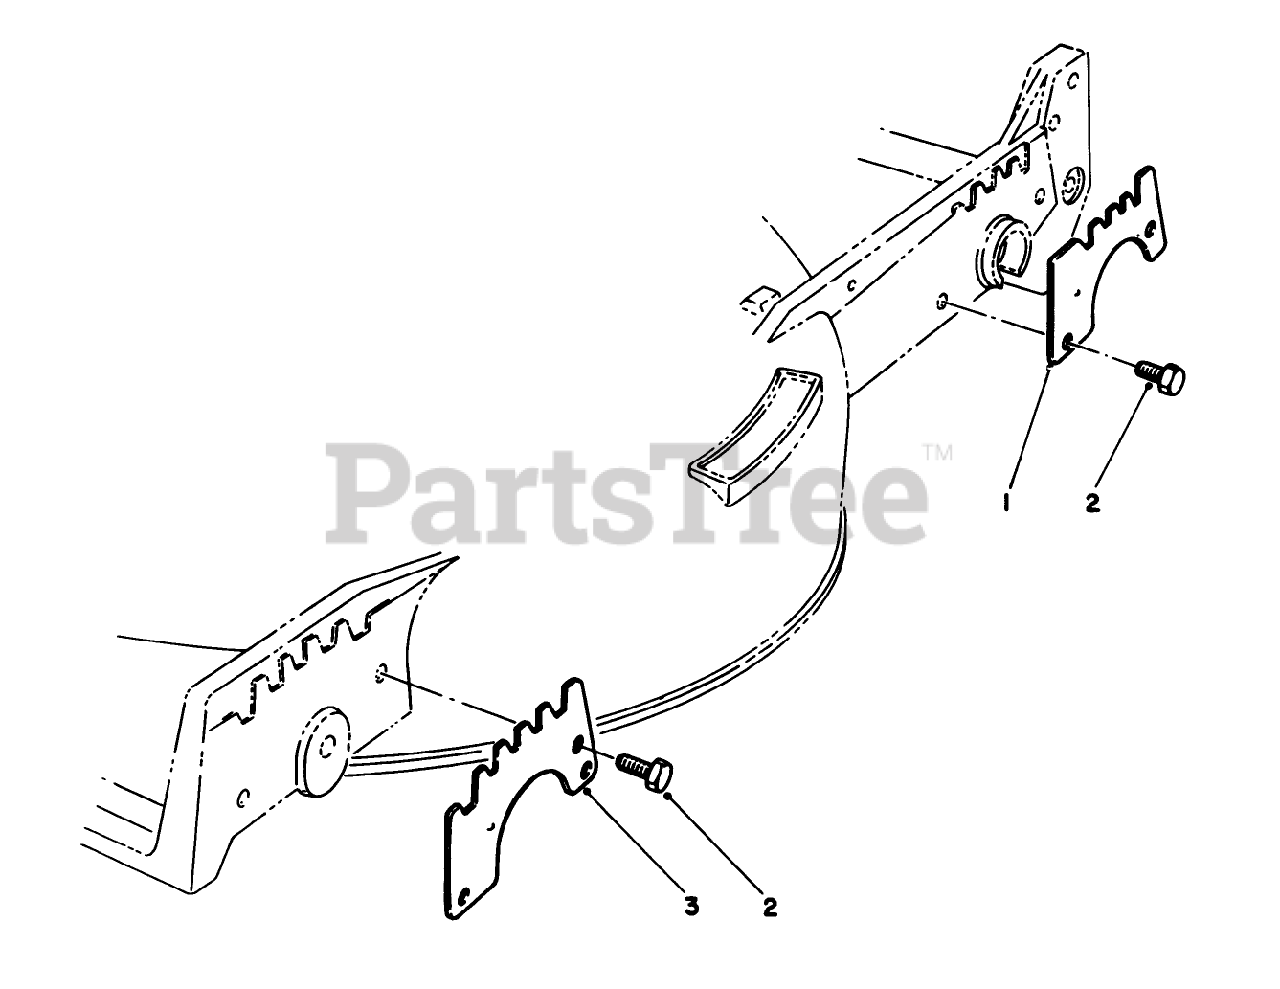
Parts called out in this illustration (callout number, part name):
1	WEAR PLATE,REAR
2	SCREW-HWH
3	WEAR PLATE
